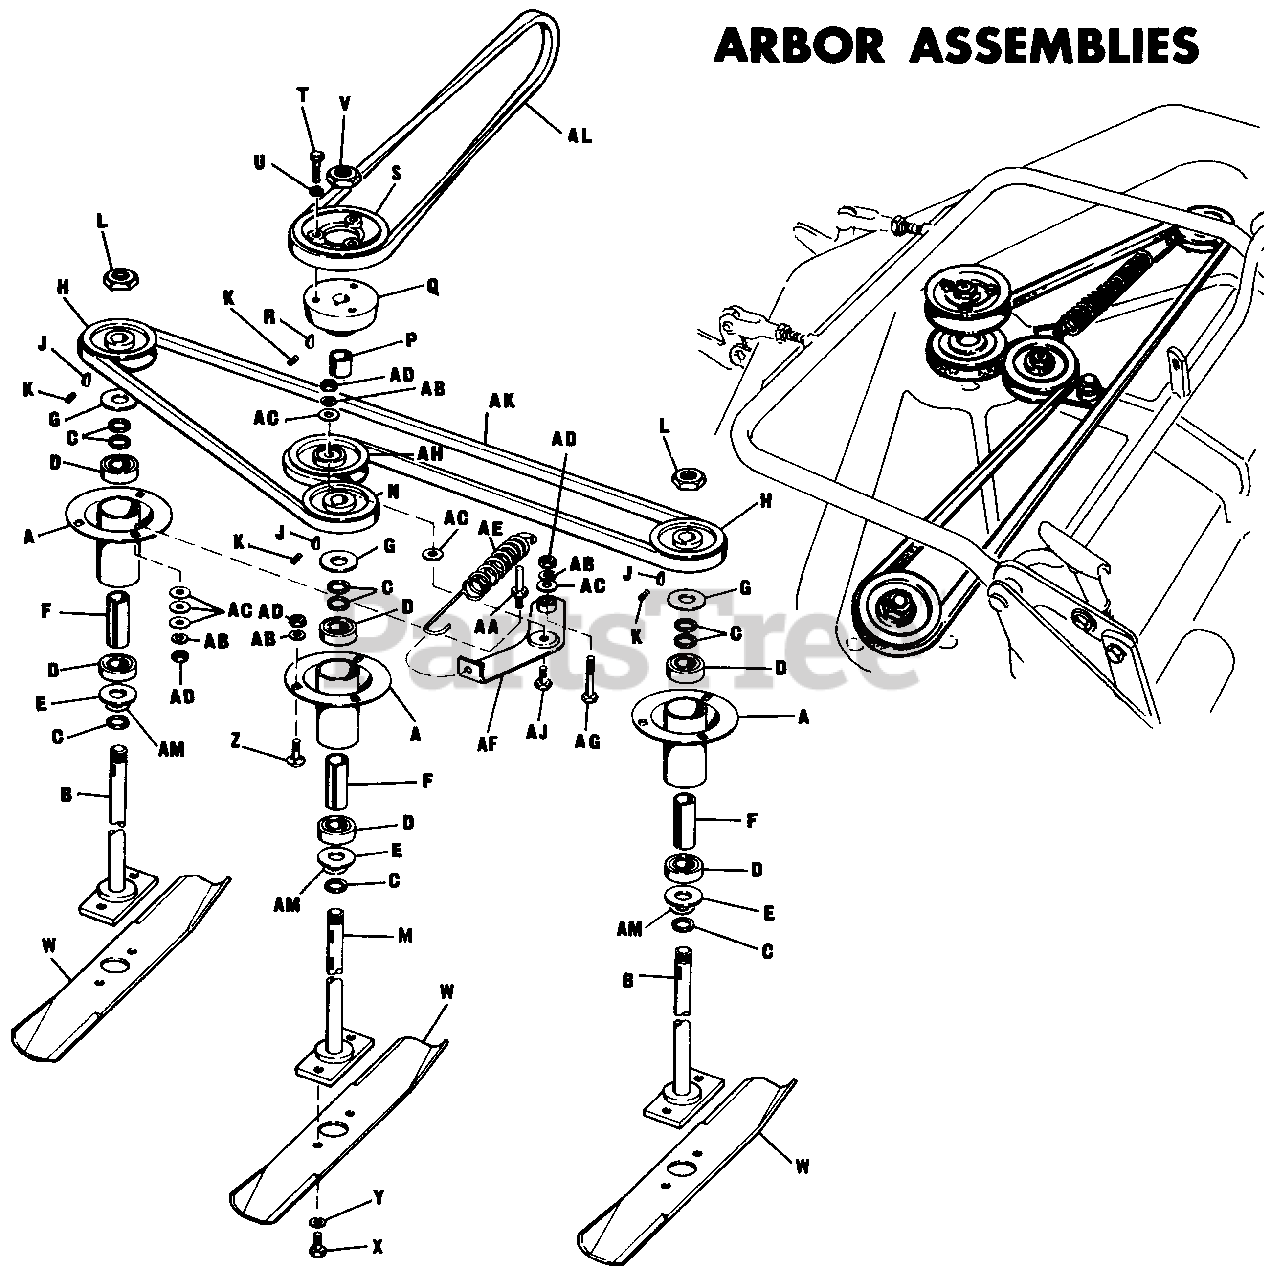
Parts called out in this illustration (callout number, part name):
A	Tube Assembly, Arbor
B	Arbor Assembly
J	Woodruff Key, #61-3/16 x 5/8"
K	Set Screw, 5/16"-18 x 3/8"
L	Hex. Lock Nut, 3/4"-16
M	Arbor Drive Assembly
R	Woodruff Key, #61-3/16" x 5/8"
T	Hex. Cap Screw, 5/16"-18 x l-1/2"
U	Lock Washer, 5/16"
V	Hex. Lock Nut, 3/4"-16
W	Knife Blade
X	Hex. Cap Screw, 3/8"-16 x 5/8"
Y	Lock Washer, 3/8"
Z	Carriage Bolt, 3/8"-16 x 3/4"
AB	Lock Washer, 3/8"
AC	Plain Washer, 5/16"
AD	Full Hex Nut, 3/8"-16
AE	Tension Spring
AF	Idler Lever Assembly
AG	Hex. Cap Screw, 3/8"-16 x 1-3/4"
AH	Idler Pulley
AL	BELT, A-Sect, 45.10
